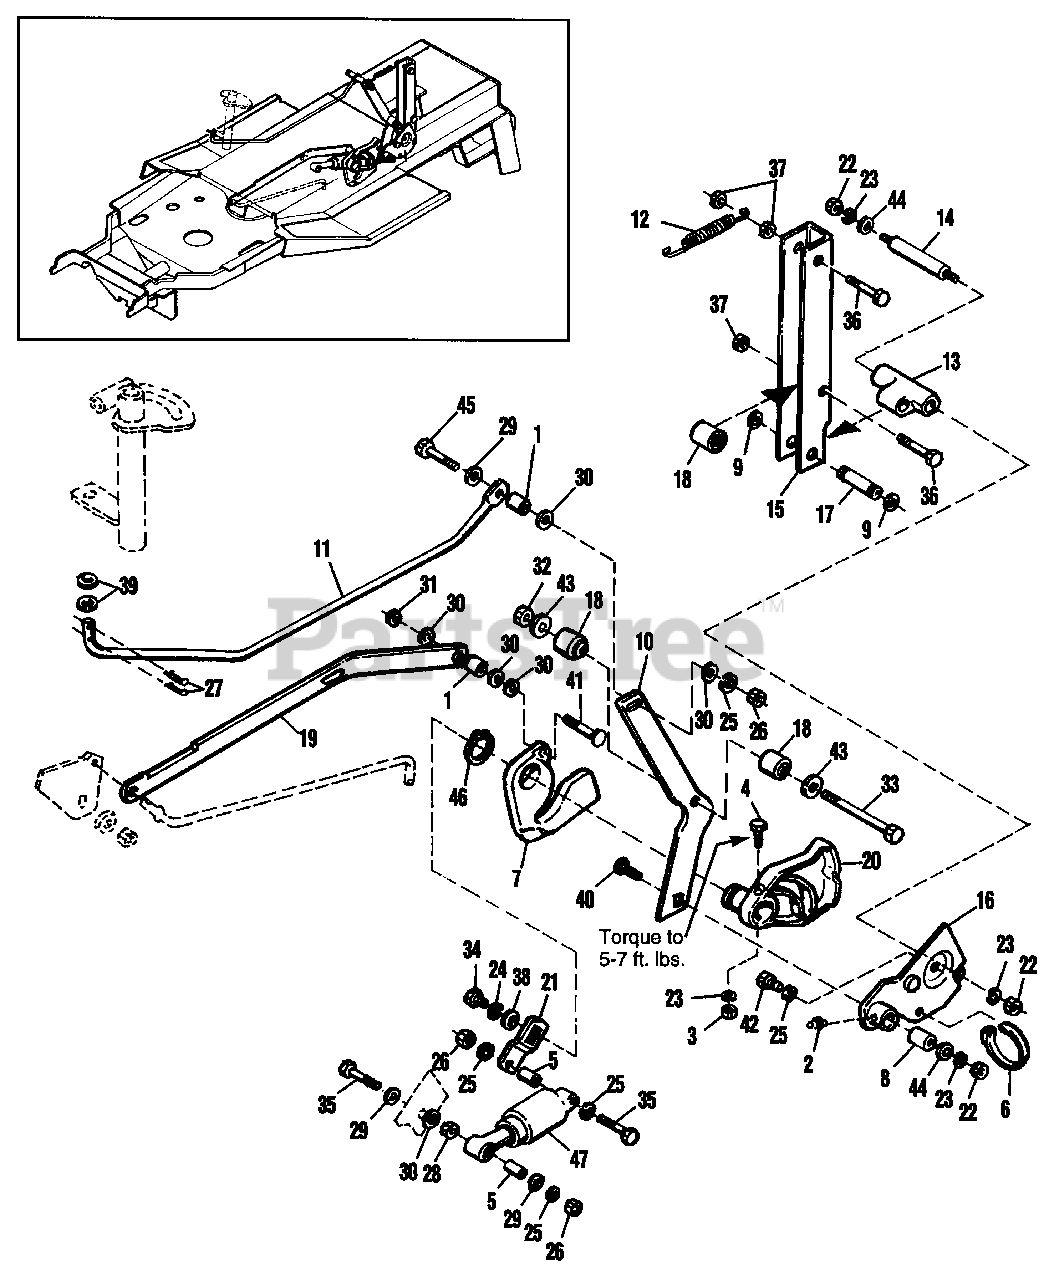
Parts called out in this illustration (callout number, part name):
2	FITTING, Lube 1/4
3	NUT, Hex, 6 mm-1.0
4	CAPSCREW, Hex, 6 mm-1.0 x 55 mm
6	TIE, Self-Locking
7	CAM, Neutral Return
9	RING, Retaining, Ext. 3/8
10	LEVER, Speed Control
12	SPRING, Extension
13	LEVER, Neutral Adj.
14	PIVOT, Adj. Lever
15	ARM, Neutral Roller
16	BRACKET, Control Support
18	ROLLER, Cam
19	ROD, Return-To-Neutral
20	CAM CONTROL ASSY.
22	NUT, Hex, 1/4-20
23	LOCKWASHER, 1/4
24	LOCKWASHER, 3/8
25	LOCKWASHER, 5/16
26	NUT, Hex, 5/16-18
27	PIN, Cotter
28	NUT, Hex, 1/2-20
29	WASHER, 11/32 x 3/4 x 1/16
30	WASHER, Flat, 11/32 x 1 x 1/8
31	NUT, Hex Lock, Esna, 5/16-18
32	NUT, Hex, Lock, Esna, 1/4-20
33	CAPSCREW, Hex, 1/4-20 x 2-1/4
34	CAPSCREW, Hex, 3/8-16 x 3/4
35	CAPSCREW, Hex, 5/16-18 x 1-3/4
36	CAPSCREW, Hex, 1/4-20 x 1-1/2
37	NUT, Hex, Center Lock, 1/4-20
38	WASHER, 13/32 x 1-1/2 x 1/8
39	WASHER, Plain
40	CARRIAGE BOLT, 1/4-20 x 2
41	CARRIAGE BOLT, 5/16-18 x 1-3/4
42	CAPSCREW, Hex, 8 mm-1.25 x 19 mm
43	WASHER, Flat
44	WASHER, Flat, 1/4
45	CAPSCREW, Truss, Socket Hd., 5/16-18 x 1-1/4
46	RING, Retaining
47	SHOCK ABSORBER
